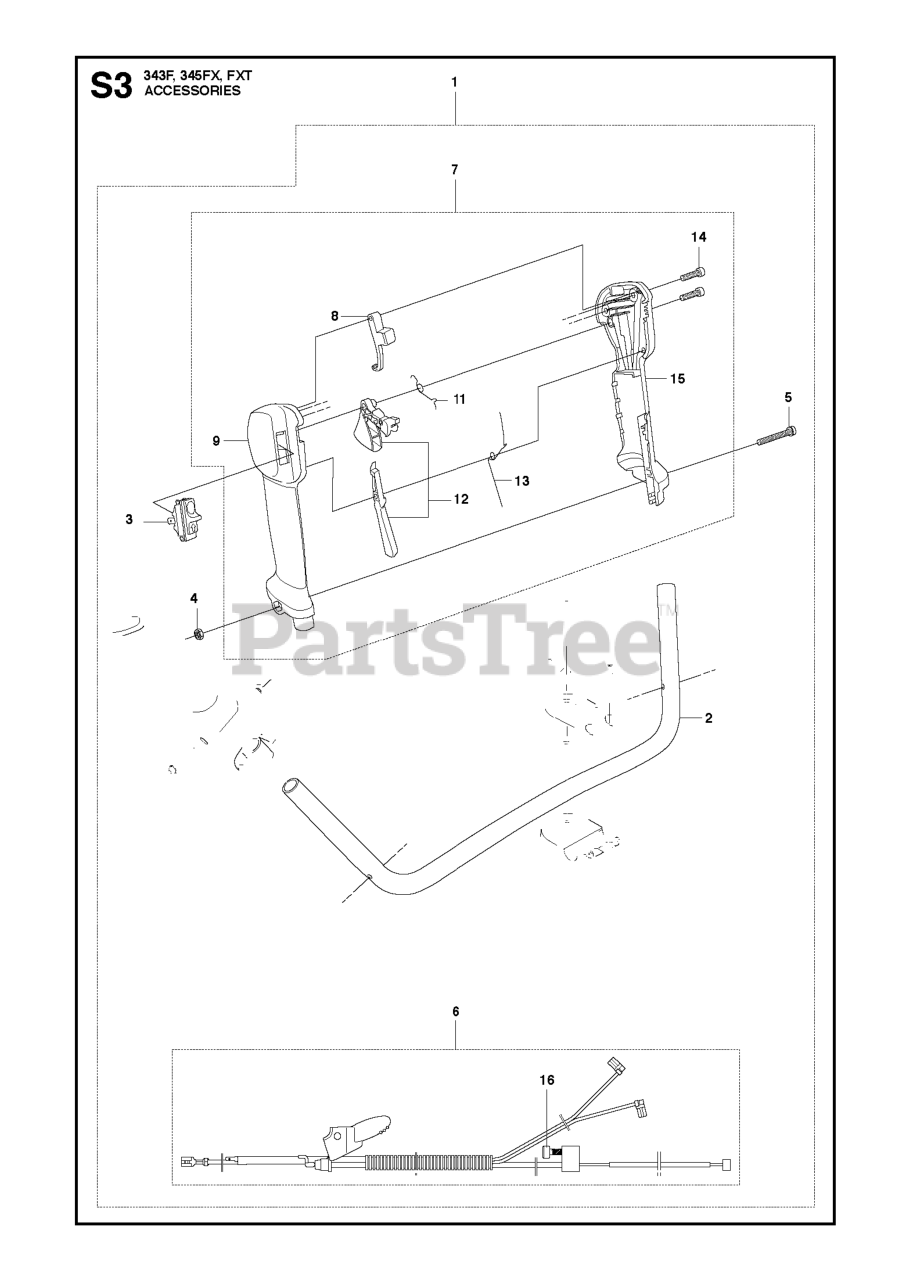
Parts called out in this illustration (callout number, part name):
2	HANDLE
5	SCREW
6	WIRING ASSY
7	THROTTLE HANDLE ASSY
8	LOCKOUT STARTER THROTTLE
9	HANDLE HALF LEFT
12	THROTTLE CONTROL
15	HANDLE HALF RIGHT
16	SCREW
